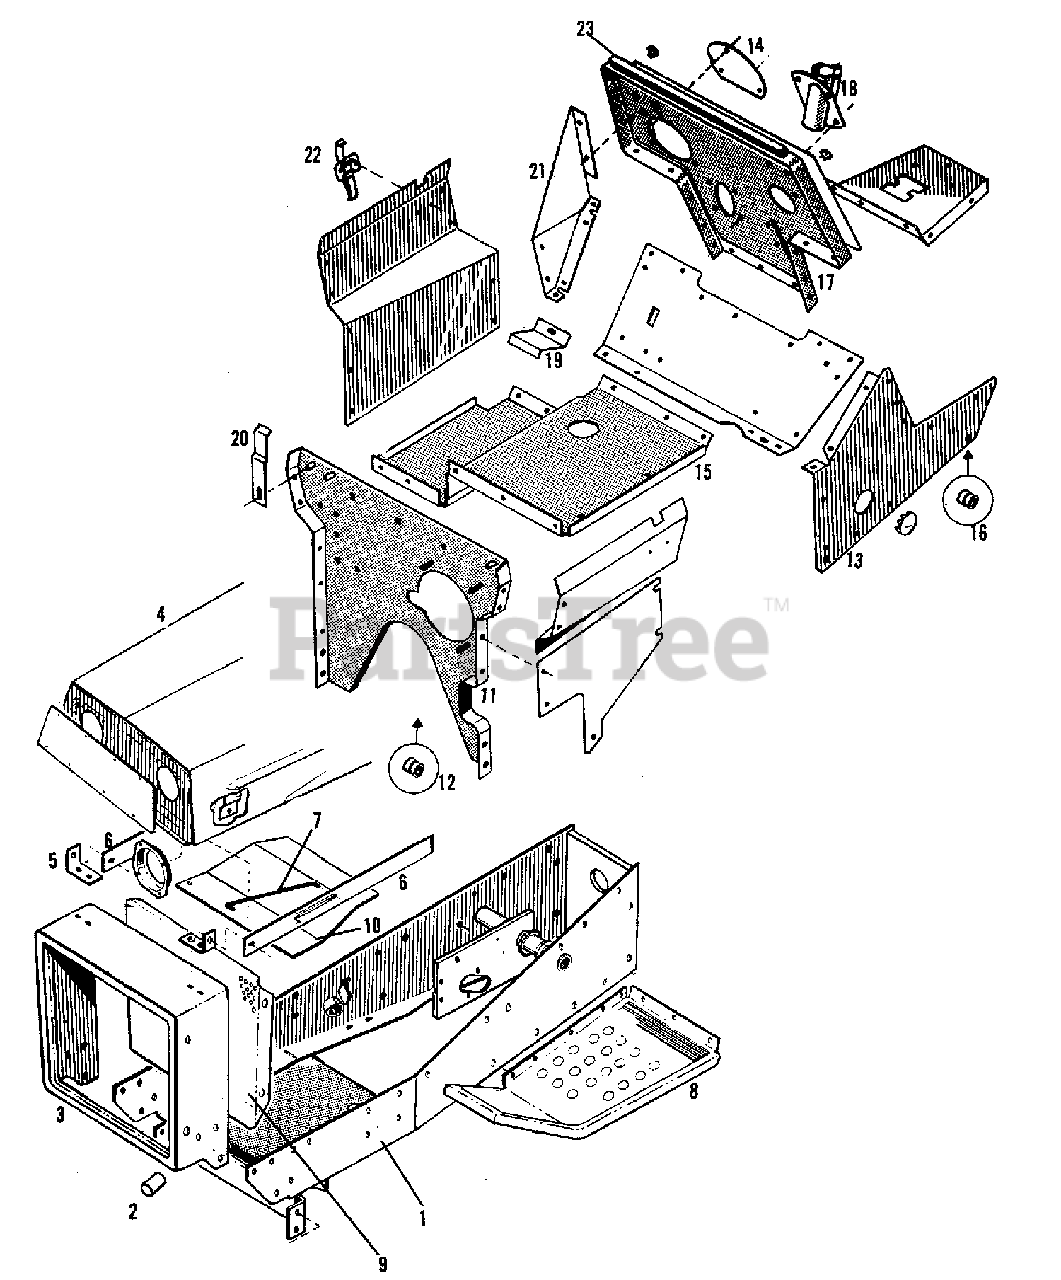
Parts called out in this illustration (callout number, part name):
1	FRAME ASSEMBLY, Main (Prior S/N 25841001, 26041001, 26141001, &, 29941001)
1	FRAME ASSEMBLY, Main (Eff. S/N 25841001 & Up, 26041001 & Up, 26141001 & Up, 29941001 & Up)
1	FITTING, Drive
2	BEARING, Sleeve
3	HOUSING ASSEMBLY, Grille
3	SCREW, 5/16NC x 1" Taptite
4	HOOD ASSEMBLY
4	RIVET, 3/16 x .527 Pop Type
5	BRACKET, Grille Brace
5	CAPSCREW, 5/16NC x 5/8
5	LOCKWASHER, 5/16
5	NUT, 5/16NC
6	BRACE, Grille
6	CAPSCREW, 5/16NC x 5/8
6	CCAPSCREW, 5/16NC x 3/4
6	LOCKWASHER, 5/16
6	NUT, 5/16NC
6	WASHER, 5/16
7	ROD, Hood Lift
7	WASHER, 7/64 x 5/8 x 18 Ga
7	PIN, 3/32 x 1/2 Cotter
8	FOOTREST, R.H.
8	FOOTREST, L.H.
8	SCREW, 1/4NC x 5/8
9	INSERT, Grille
9	CAPSCREW, 1/4NC x 5/8
9	WASHER, 17/64 x 1 x 16 Ga
9	LOCKWASHER, 1/4
9	NUT, 1/4NC
10	SHIELD, Engine
11	WALL, Front Support
11	CAPSCREW, 5/16NC x 3/4
11	LOCKWASHER, 5/16
11	NUT, 5/16NC
11	SCREW, 5/16NC x 1/2 Taptite
12	GROMMET, Rubber
13	SHEET, R.H. Side
13	SHEET, L.H. Side
13	NUT, J-Type Retainer
13	NUT, U-Type Speed
13	NUT, 1/4NC Cage Retainer
14	COVER, Control Linkage
14	RIVET, Pop 1/4NC x .472
15	FLOOR, Fuel Tank
15	RIVET, Pop 1/4NC x .472
16	GROMMET, Rubber
17	PANEL, Instrument
17	RIVET, Pop 1/4NC x .472
17	RIVET, Pop 3/16 x .402 (Black)
17	CAPSCREW, 1/4NC x 5/8
17	LOCKWASHER, 1/4
17	NUT, 1/4NC Cage Retainer
17	CAPSCREW, 1/4NC x 1-1/4 (Full Thread)
17	NUT, 1/4NC
17	SCREW, 1/4NC x 1/2 Taptite
18	CLAMP ASSEMBLY, Steering Post
18	CAPSCREW, 1/4NC x 5/8
19	STOP, Battery
19	BOLT, 5/16NC x 5/8, Carriage
19	WASHER, 5/16, Standard
20	CLAMP, Battery
20	BOLT, 5/16NC x 3/4, Carriage
21	PANEL, Side
21	SCREW, 1/4NC x 1/2, Taptite
21	SCREW, 1/4NC x 5/8, Taptite
22	LATCH, Hood
22	SCREW, #10NC x 3/8 Round Head, Machine
22	LOCKWASHER, #10 Ext. Tooth
22	NUT, #10NC
23	TAPE, Foam (14-1/2" Length)
24	INSULATOR, Instrument
